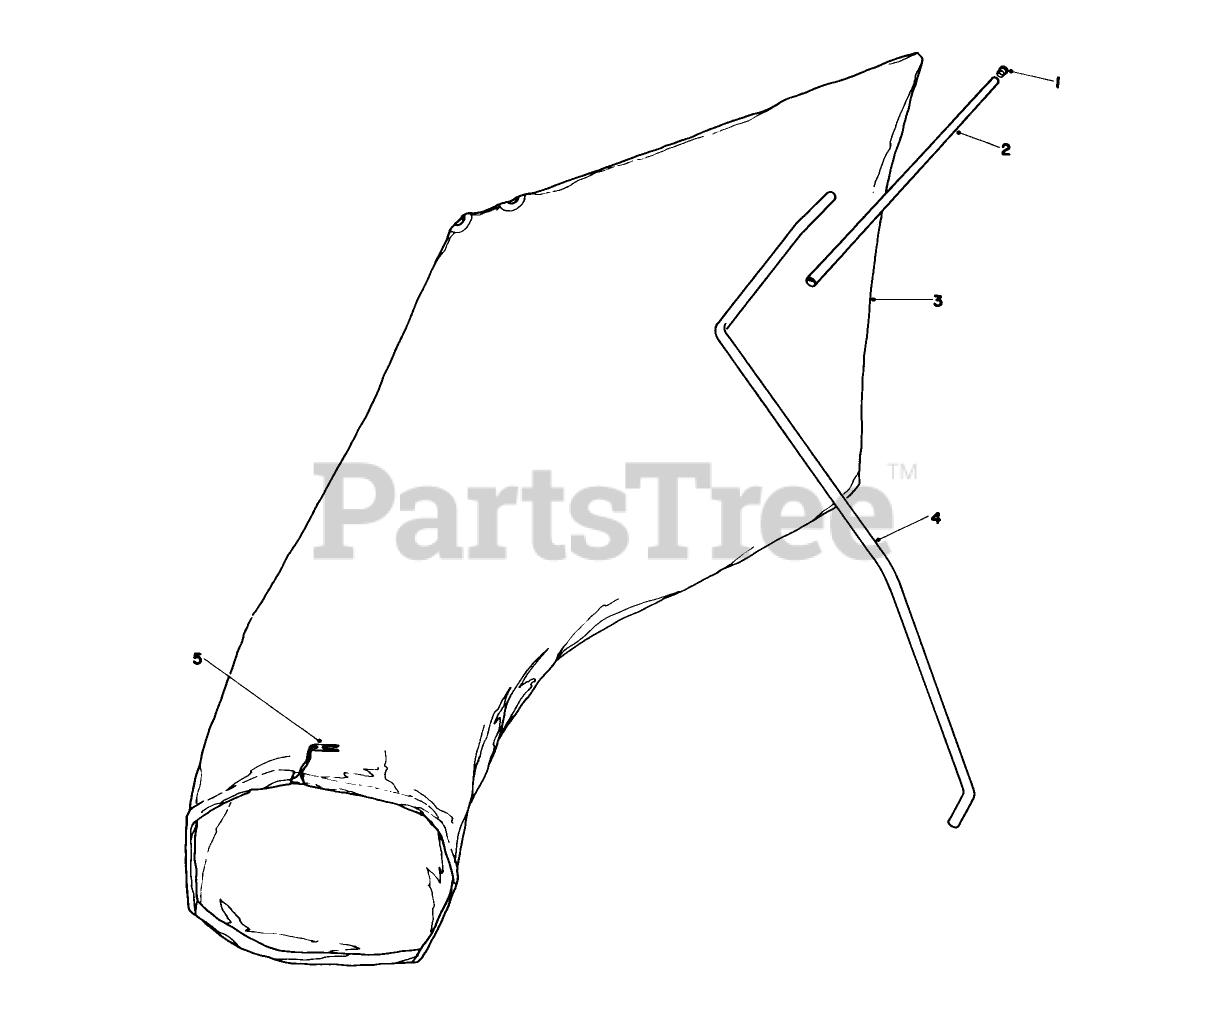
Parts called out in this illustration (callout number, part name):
2	BAG HANGER TUBE
3	Bag (Incl. Ref. #5)
4	HANGER ROD
5	BAG CORD FASTENER
